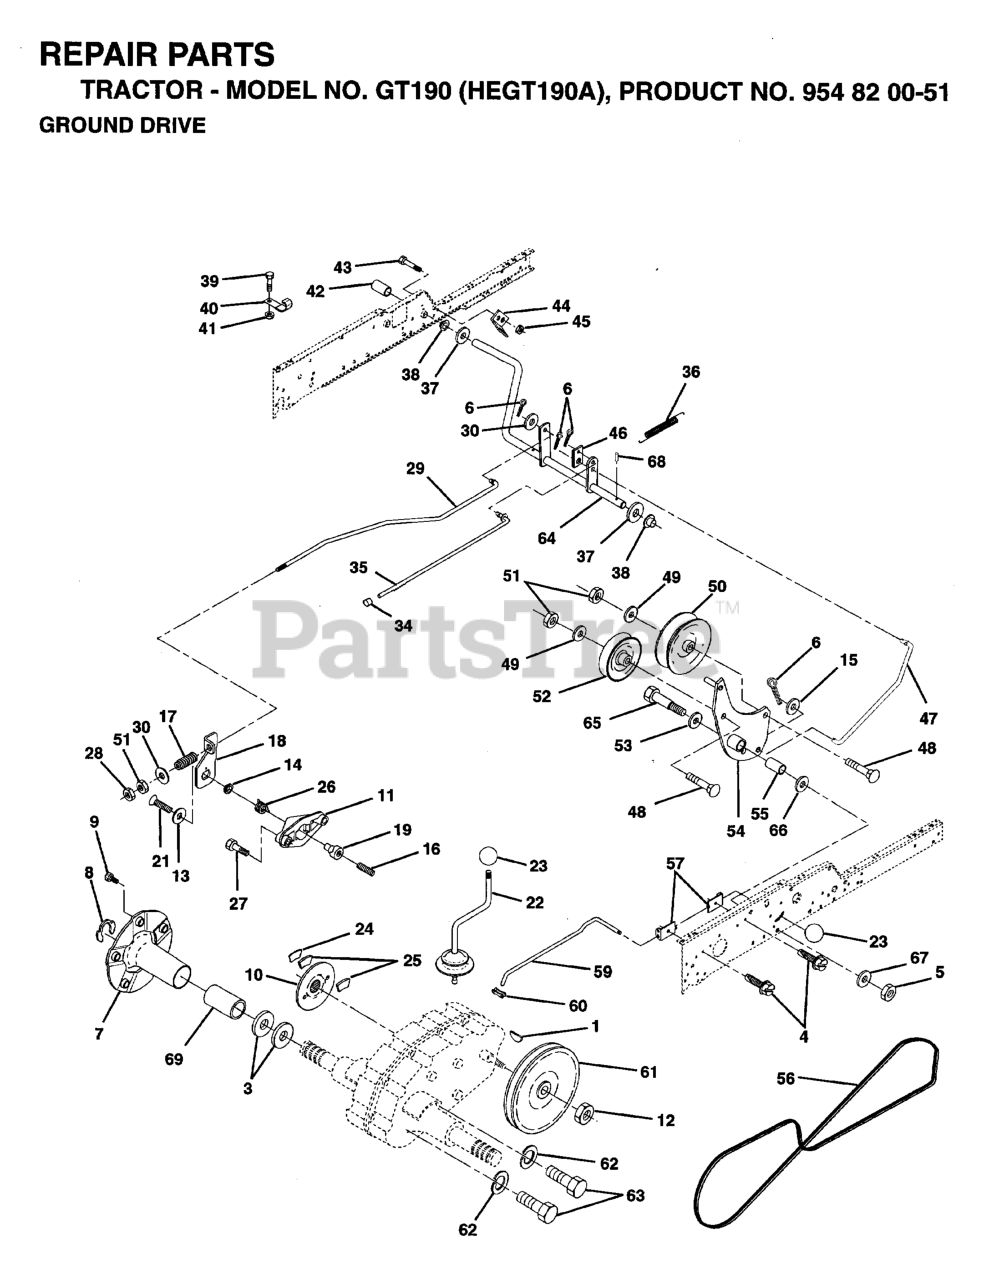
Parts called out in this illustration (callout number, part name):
1	KEY
4	Screw 5/16-18 x 1/2 Hex, Self Tapping 5/16-18 x 1/2
6	COTTER PIN
7	HUB.WHL.ASM.REAR
8	Ring, Klip Truarc #5304-75
10	DISC BRAKE
11	YOKE-BRAKE DISC
15	WASHER
17	SPRING,ROD BRAKE
18	BRAKE LEVER
19	BRAKE DISC CAM
21	Screw, Flat Head 1/4-28 x 3/4
22	GEAR SHFT LVR T
24	BRAKE PUCK SUPPORT
25	BRAKE PUCK TOP
26	RETURN SPRING
28	NUT
29	ROD BRAKE ZINC GT
30	WASHER
31	COTTER PIN
34	PLUNGER CAP
35	PARKING BRAKE ROD
36	SPRING DRIVE GROUND
39	Screw, Fin. #10-24 x 1
40	ACT-SWITCH T
41	LOCKNUT
42	COVER, PEDAL (1 2)
43	BOLT.HEX.1/4.X.3/4.DICHROMATE
44	BRKT SWITCH GT
45	LOCKNUT.NYLOC.1/4-20
46	RETAINER SPRING
47	CLUTCH ROD
49	Washer 13/32 x 7/8 x 13 Gauge
50	FLAT IDLER PULLEY
52	PULLEY.IDLER.V.
54	CLUTCH ARM ASSY
55	BEARING LT (2 2)
56	V-BELT GROUND DRIVE
57	BRACKET SHIFT ROD
59	ROD SHIFT HI LO
60	CONNECTING LINK
61	TRANSAXLE PULLEY
62	LOCKWASHER
63	BOLT
64	PEDAL SHAFT
66	WASHER.BLADE
67	WASHER
68	ROLL PIN STD
69	COVER.HUB.BLACK
